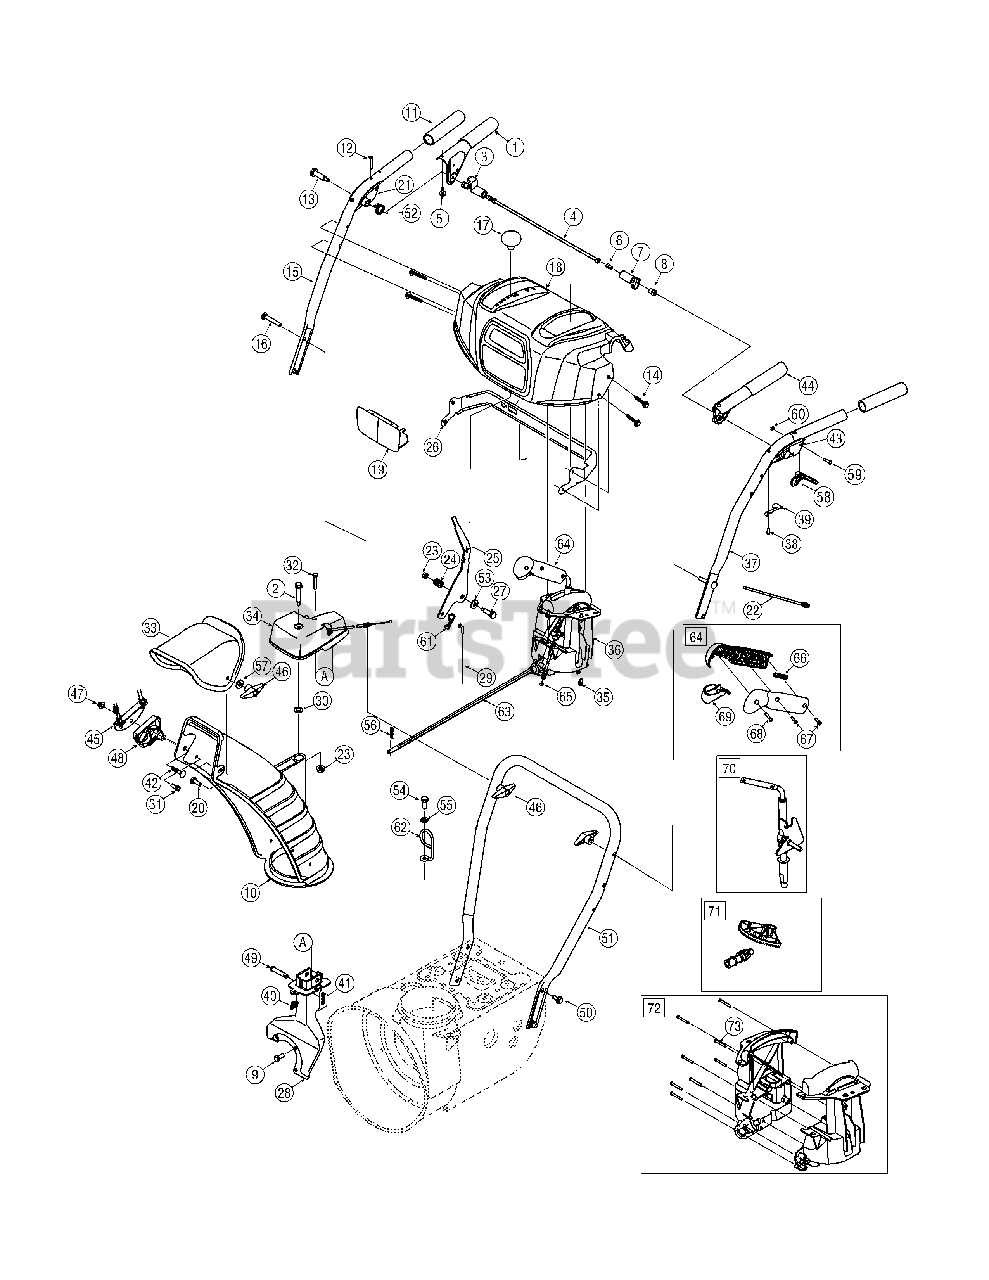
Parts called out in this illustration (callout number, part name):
1	Handle Engagement Assembly RH
2	Flange Shoulder Screw
3	Lock Plate
4	Pivot Rod
5	Rubber Bumper
6	Screw, 1/4-20 x .500
7	Clutch Lock Cam
8	Shoulder Nut, 1/4-20
9	Hex Screw, 5/16-24 x .750
10	Lower Chute
11	Handle Grip
12	Screw, #10-24 x 0.375
13	Shoulder Screw, 1/4-20
14	Screw, 1/4-20 x 1.625
15	Upper Handle RH
16	Carriage Screw, 5/16-18 x 2.25
17	Shift Knob
18	Handle Panel
20	Carriage Bolt, 5/16-18 x 1.0
21	Handle Clutch Lock RH Assembly
22	Cable Tie
23	Flange Lock Nut, 1/4-20
24	Compression Spring
25	Shift Lever
26	Panel Bracket
27	Shoulder Screw
28	Chute Support Bracket
29	Speed Selector Cable
30	Flat Washer, .25 x .630 x .0515
31	Hi-Lo Screw, 1/4-15 x .75
32	Hex Screw, 1/4-20 x 3.00
33	Upper Chute
34	4-Way Chute Gearbox Assembly
35	Hi-Lo Screw, 1/4-15 x 0.5
36	4-Way Chute Control™ Assembly
37	Upper Handle LH
38	Screw, #8-16 x 0.50
39	Clutch Lock Spring
40	Wing Nut, 1/4-20
41	Bow Tie Cotter Pin
42	Carriage Bolt, 5/16-18 x 1.50
43	Handle Clutch Lock LH Assembly
44	Handle Engagement Assembly LH
45	Cable Bracket
46	Wing Knob
47	Flange Lock Nut, 5/16-18
48	Chute Tilt Cable Guide
49	Clevis Pin
50	Screw, 5/16-18 x 0.75
51	Lower Handle
52	Torsion Spring
53	Flat Washer
54	Screw, M8-1.25
55	Flat Washer, .330 x .630 x .0635
56	Cotter Pin
57	Flat Washer, .349 x .879 x .063
58	Steering Control
59	Pin, 3/16
60	E-Ring
61	Click Pin
62	Cable Control Wire
63	Chute Rod
64	Handle Assembly
65	4-Way Cable
66	Handle Plunger
67	Screw, Mach., #8-32 x .750
68	Screw, #8 x 1.00
69	Handle Lever
70	Shift Assembly
71	Gear Set Assembly
72	Handle Housing Assembly
73	Screw, #8-18 x 1.250
